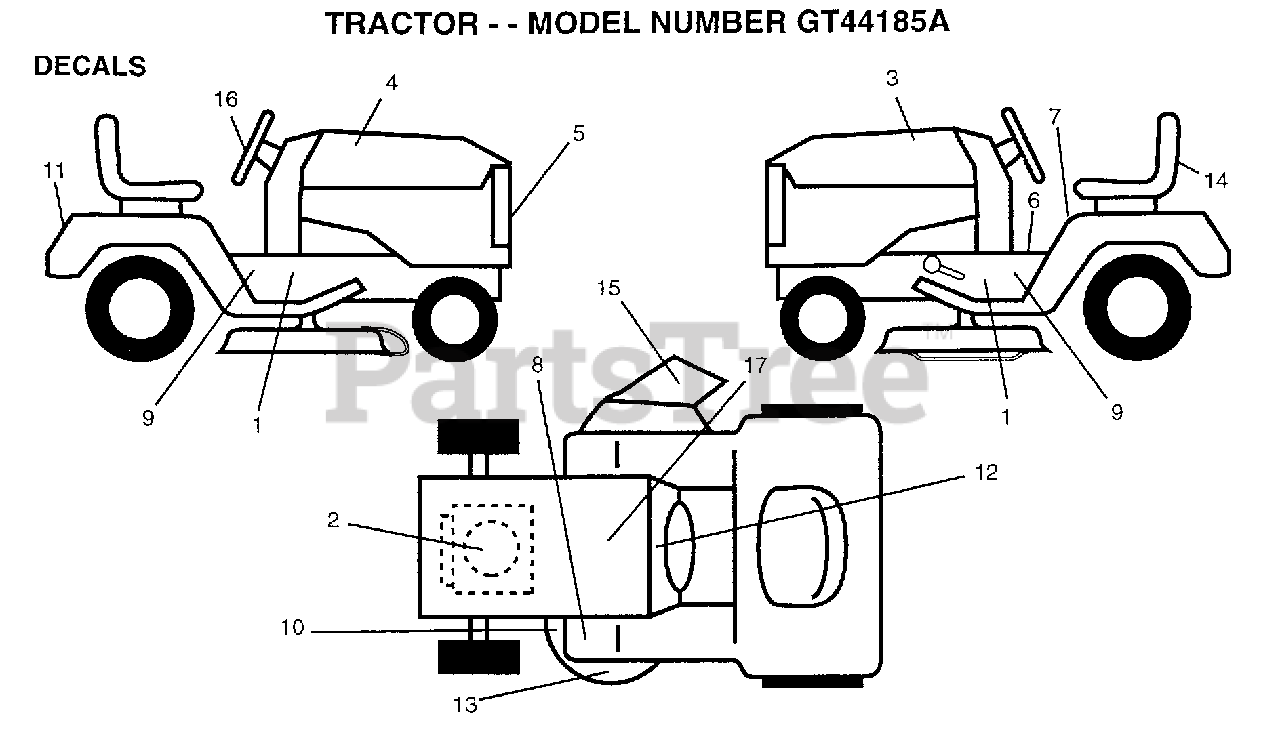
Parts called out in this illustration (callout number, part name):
1	DECAL.CHAS.KGRO
2	DECAL, HP, ENGINE
3	DECAL.HD.LH.KGRO
4	DECAL.HD.RH.KGRO
5	DECAL LOGO GRILLE
6	DECAL BRAK PARK
7	DECAL CAUT FEND
8	DECAL CLUT/BRAKE
9	DECAL CHASSIS YT
10	"DECAL.V.BELT.44"""
11	DECAL.FEN.GT.KMAR
12	DECAL INST OP DAS
13	DECAL.DECK.KGRO.
14	"DECAL-SEAT,K GRO"
15	DECAL DANGER CT/F
16	DECAL INST WHL
17	DECAL.BTRY.DANGER
